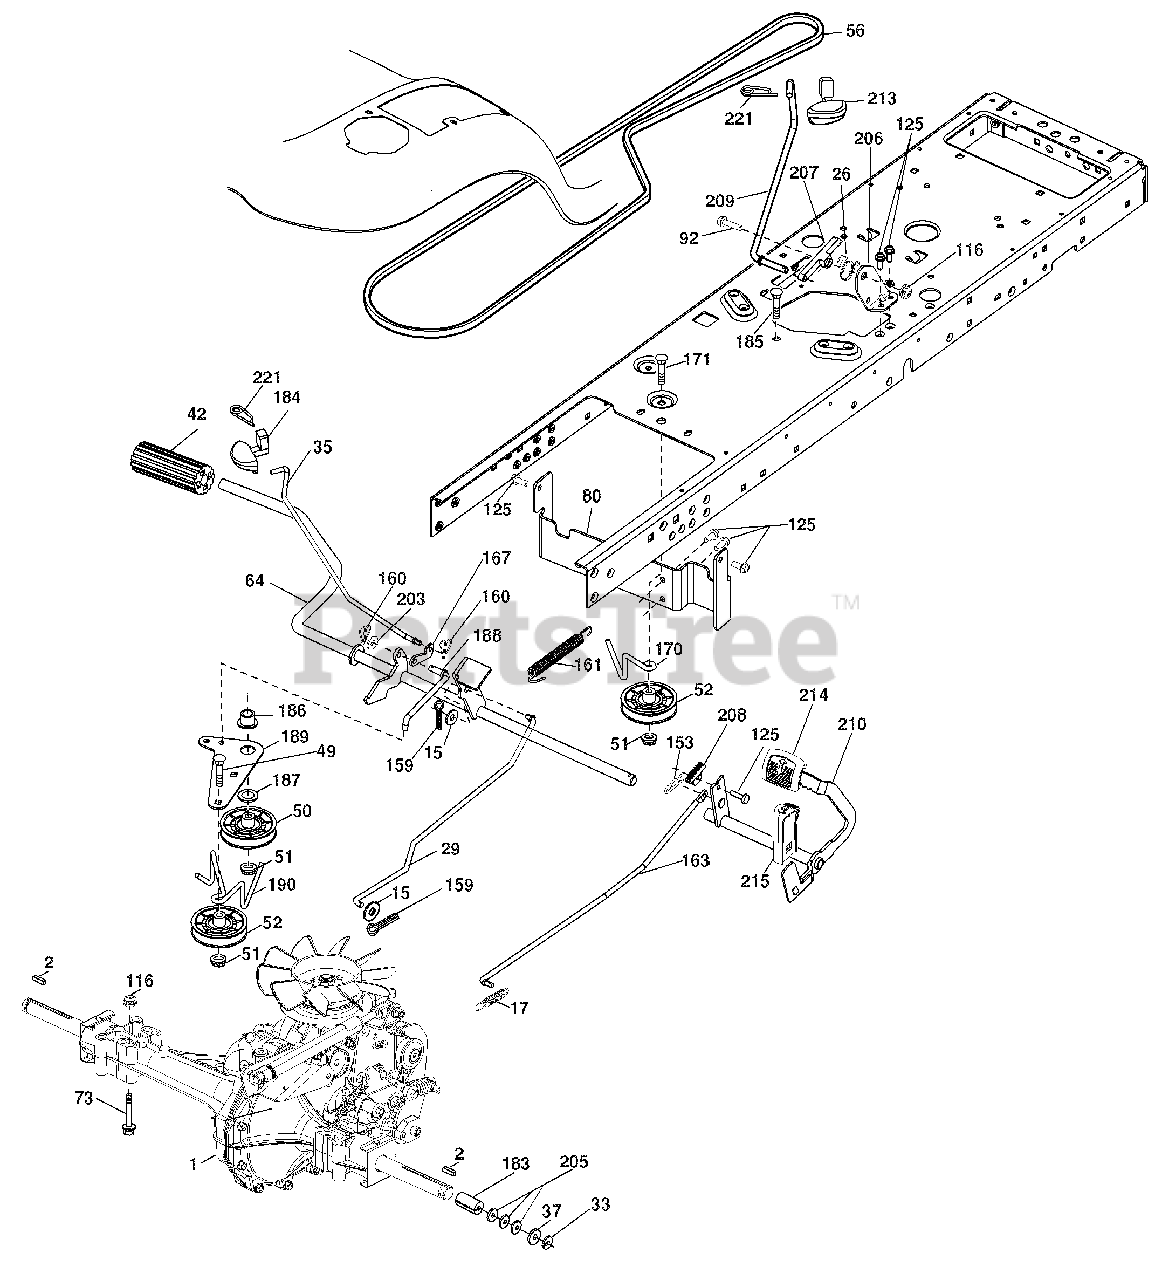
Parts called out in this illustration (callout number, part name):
2	Key Square
15	Washer 13/32 x 13/16 x 16 Ga.
17	Spring, Brake
26	Spring Return Cruise
29	Rod, Brake
35	Rod, Brake, Park
37	Washer 25/32 x 1-1/4 x 16 Ga.
42	Cover, Foot Pedal
50	Pulley Idler Flat
51	Lock Nut 3/8-16
52	Idler V-Groove 910" Offset
56	V-Belt, Drive
64	Shaft Asm. Pedal Brake Control
73	Bolt Hex Flghd 5/16-18 x 3.0 Gr. 5
80	Bracket Strap Torque
92	Bolt Fin Hex 5/16-18 unc x 1.25
116	Nut Lock Hex Flange 5/16-18
125	Screw 5/16-18 x 3/4
153	Retainer Spring
159	Pin Cotter 1/8 x 3/4
160	Retainer Clip
161	Spring, Return, Clutch
163	Rod Pedal Control
167	Latch Brake Parking
170	Keeper Belt Centerspan
183	Spacer Axle
184	Handle Parking Brake
186	Spacer Retainer
187	Washer
188	Link Clutch Ground Drive
189	Bellcrank Ground Drive
190	Keeper Bellcrank Ground Drive
196	Screw 3/8-16 x 1
197	Link Clutch Anti-Rotation
203	Washer 11/32 x 11/16 x 16 Ga.
205	Washer 25/32 x 1-5/8 16 Ga.
206	Bracket Mount Latch Cruise
207	Latch Control Cruise
208	Gear Sector Control Cruise
209	Rod Control Cruise
210	Rockr Asm. Pedal Control
213	Knob control Cruise
214	Pad Pedal Forward
215	Pad Pedal Reverse
221	Retainer Spring Clip
